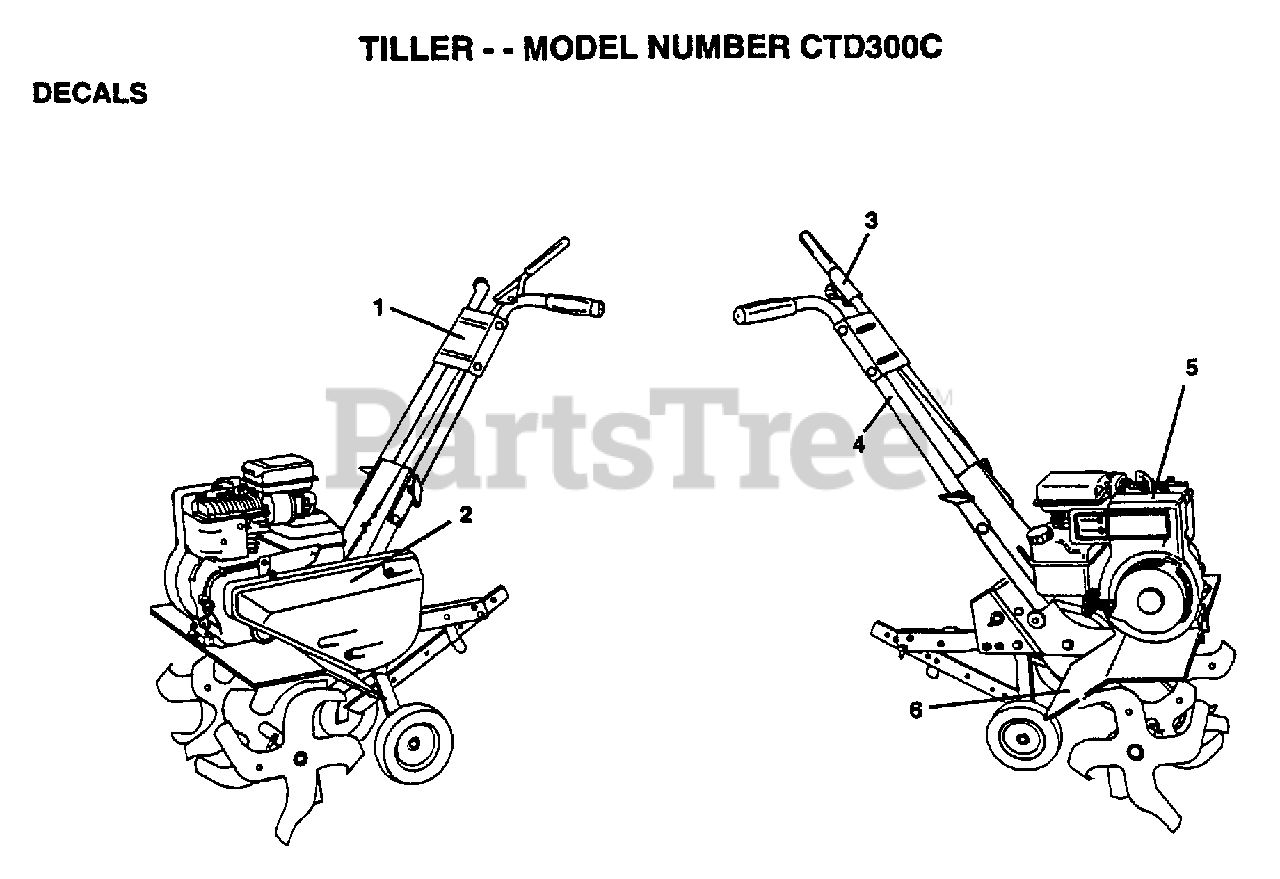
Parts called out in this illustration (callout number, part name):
1	DECAL PNL CNTL
2	DECAL.GUARD.BELT
3	DECAL TI
4	DECAL TI
6	DECAL TI
